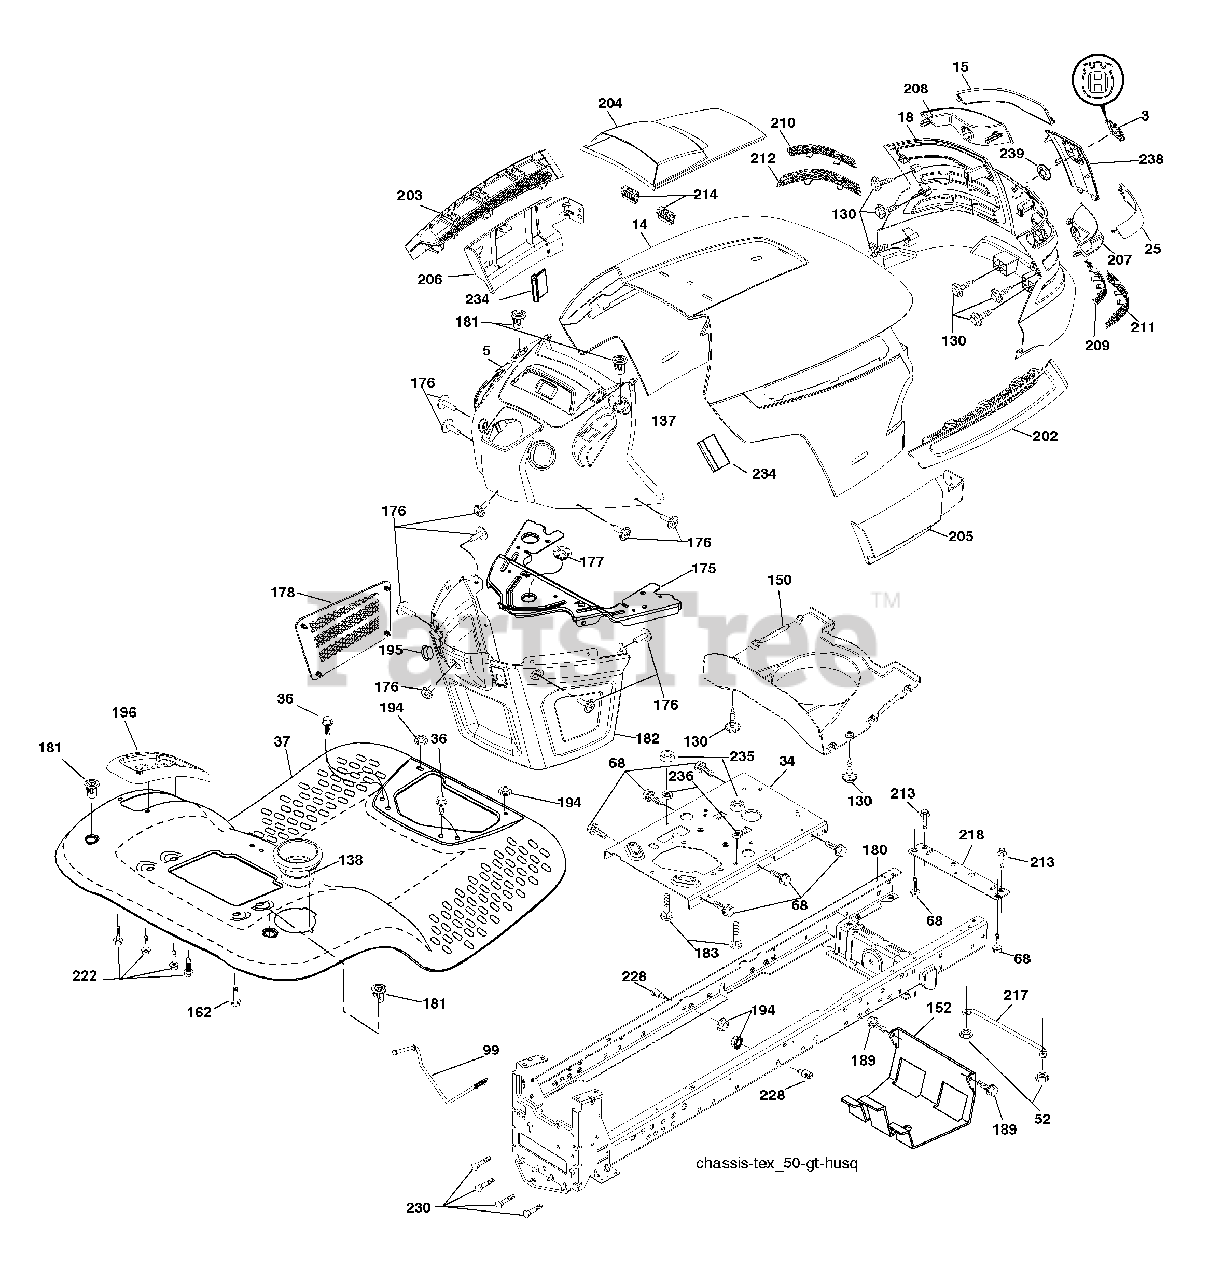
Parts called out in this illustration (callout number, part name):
3	Logo
14	Hood
18	Grille Asm.
34	Plate Engine
36	Screw 5/16-18 x 3/4
37	Fender
52	Nut Lock 5/16-18
68	Screw 5/16-18 x 1/2
99	Rod Asm Bypass
130	Screw 10 x 3/4 Single Lead-Hex
138	Cupholder
152	Shield Browning
175	Crossmember
176	Screw 10-24 x 5/8
177	Bushing Steering
178	Cargo Net Asm.
180	Chassis
181	Bushing Mtg. Fender Crgo
182	Dash Lower
183	Bolt Fin Hex 5/16-18 unc x 1-1/4
189	Screw 5/16-18 x 3/4
194	Nut Lock Hex Flange 5/16-18
195	Plug Hole Dash Lower
196	Console Asm. Deck Lift
202	Vent Side Hood RH
203	Vent Side Hood LH
204	Vent Top Hood
205	Skirt Hood Side RH
206	Skirt Hood Side LH
209	Insert Hex Top RH
210	Insert Hex Top Lh
211	Insert Hex Bottom RH
212	Insert Hex Bottom LH
213	Bolt 5/16-18 UNC x 3/4
214	Clip Retainer Tinner
217	Rod Pivot
218	X-Piece Hood Stop
222	Screw Thdrol 1/4-20 x 5/8
228	Stud Fastner
230	Bolt Shoulder 5/16 - 18
234	Bumper Hood
235	Spacer Fender
236	Nut Lock 5/16-18 UNC
